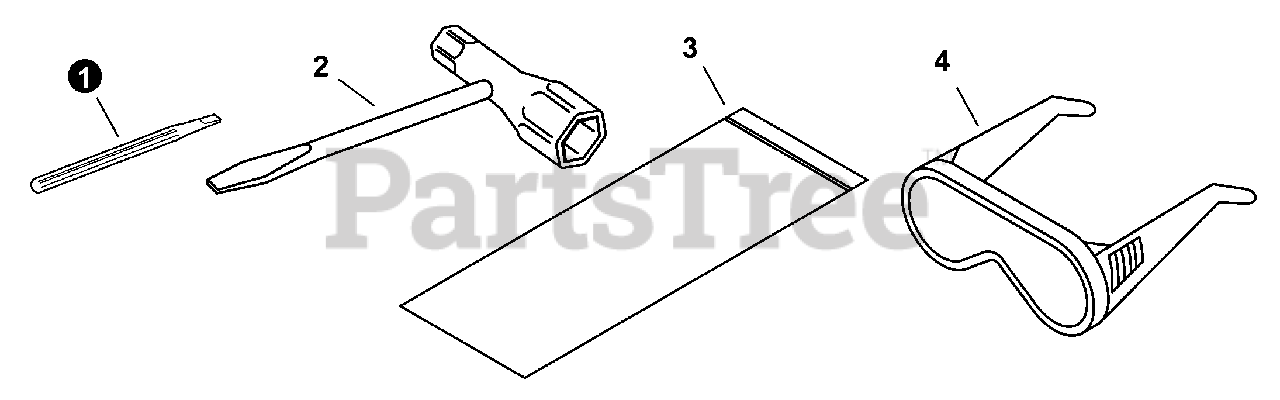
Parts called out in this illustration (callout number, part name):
1	SCREWDRIVER, PLASTIC
2	T-WRENCH
3	BAG, TOOL
4	GLASSES, SAFETY
